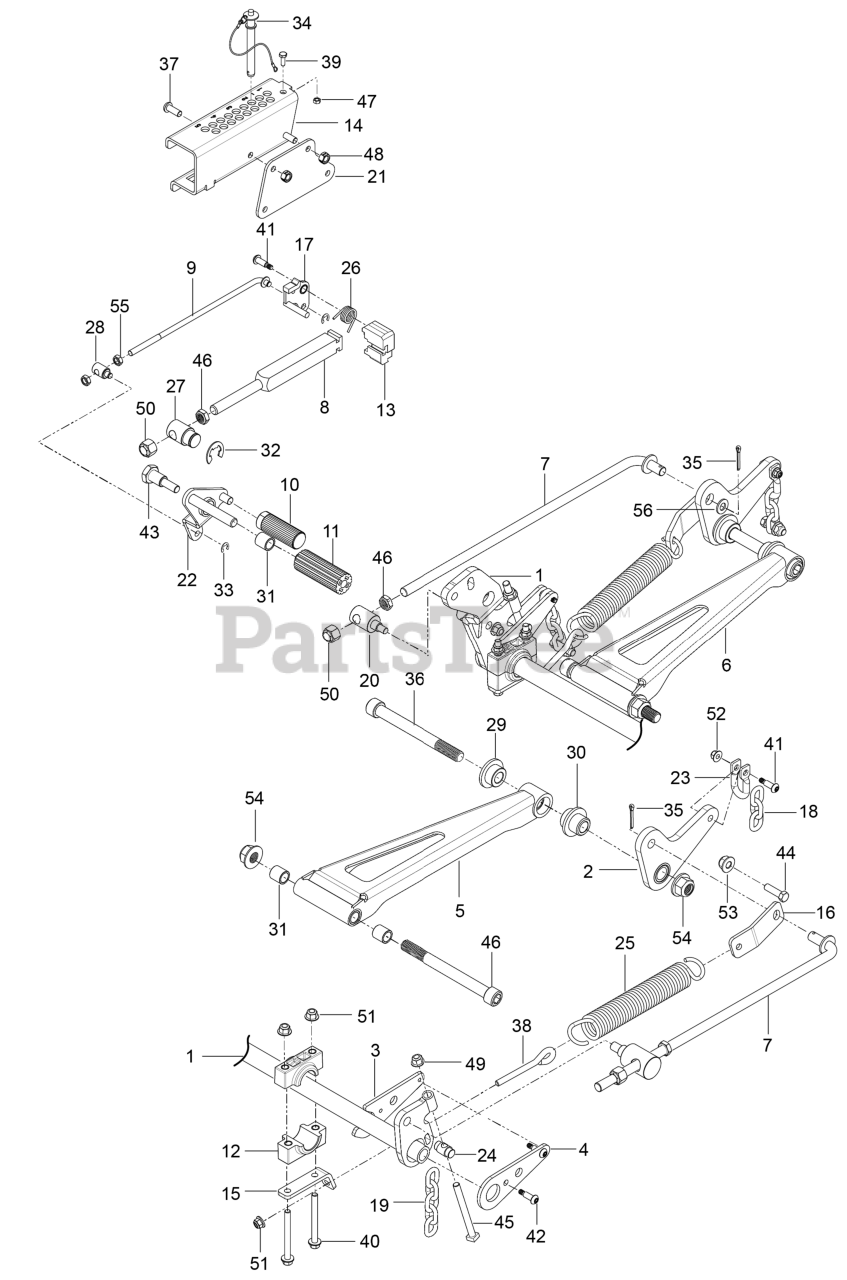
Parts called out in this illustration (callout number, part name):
1	SHAFT.WLDMNT.FRNT.DECK.LFT.PNT
2	KIT.ARM.BELLCRANK/BUSHINGS.RT
3	ARM.DECK.LIFT.INNER.BLACK
4	ARM.LIFT.DECK.OUTER.POWER.BLK
5	ARM.DRAWBAR.LH
6	ARM.DRAWBAR.RH
7	ROD. CONNECTING
8	ROD.HEIGHT.GAUGE
9	ROD.RELEASE.CONNECTING.TOE
10	PEDAL, DECK HEIGHT
11	PAD, FOOT PEDAL
12	BLOCK, PILLOW
13	BLOCK.ROD.END
14	BRACKET.ADJUSTMENT.HEIGHT.ORNG
15	BRACKET.PILLOW.BLOCK.PNT.BLACK
16	LEVER.ASM.RR.LIFT.RH.HEAVYDUTY
16	LEVER.ASM.RR.LIFT.LH.HEAVYDUTY
17	KIT.LEVER.LOCK.W/BUSHING
18	LIFT CHAIN - 3 LINK
19	LIFT CHAIN
20	PIVOT.CONNECTING.ROD
21	PLATE.HEIGHT.GAUGE.MOUNT.PNT
22	LEVER ASSY TOE RELEASE
23	SHACKLE.CHAIN
24	SHAFT.TRUNNION.ATTACH
25	SPRING EXTENSION, DECK LIFT, H
26	SPRING.TORSION.RELEASE.LEVER
27	SWIVEL.HEIGHT.BAR
28	SWIVEL.TOP.RELEASE
29	BUSHING.DECK.INNER
30	BUSHING.DECK.OUTER
31	BUSHING, SLEEVE 3/4 X 1.0
32	E-RING 1"
33	E RING 3/8"
34	PIN.PUSH.BUTTON.DETENT..5X3.5
35	COTTER PIN 1/8 X 2
36	SCREW.SOCKET.HEADCP.3/4-10X7.5
37	SCREW.BUTTON.HEAD.CAP.3/8-16X1
38	EYE BOLT, 3/8 X 4"
39	HCS 1/4C X 3/4 HCS
40	SCREW.HHFS3/8-16X3.75.GR8
41	SCREW.SHOULDER.375X875.5/16-18
42	SCREW.SHLDR..375.5/16-18.88.LG
43	BOLT, SHOULDER
44	HCS 7/16C X 1 1/2
45	SCREW.HHC.7/16-14 X 4.50
46	NUT.HH.THIN.NYL.5/8-11 GR5
47	NUT.1/4-20.HEX.NYLOC.ZD
48	NUT 3/8C CENTERBLOCK
49	7/16-14 HEX NUT W/NYL RING ZD
50	NUT 5/8-11 NYLOC
51	NUT 3/8-16 HEX FLG NYLOC ZD
52	5/16-18 NYLOC FLANGE NUT
53	NUT 7/16-14 HEX WHIZ LK
54	NUT.HEX.FLANGED.3/4-10.NYLOK
55	NUT 3/8-24 JAM
